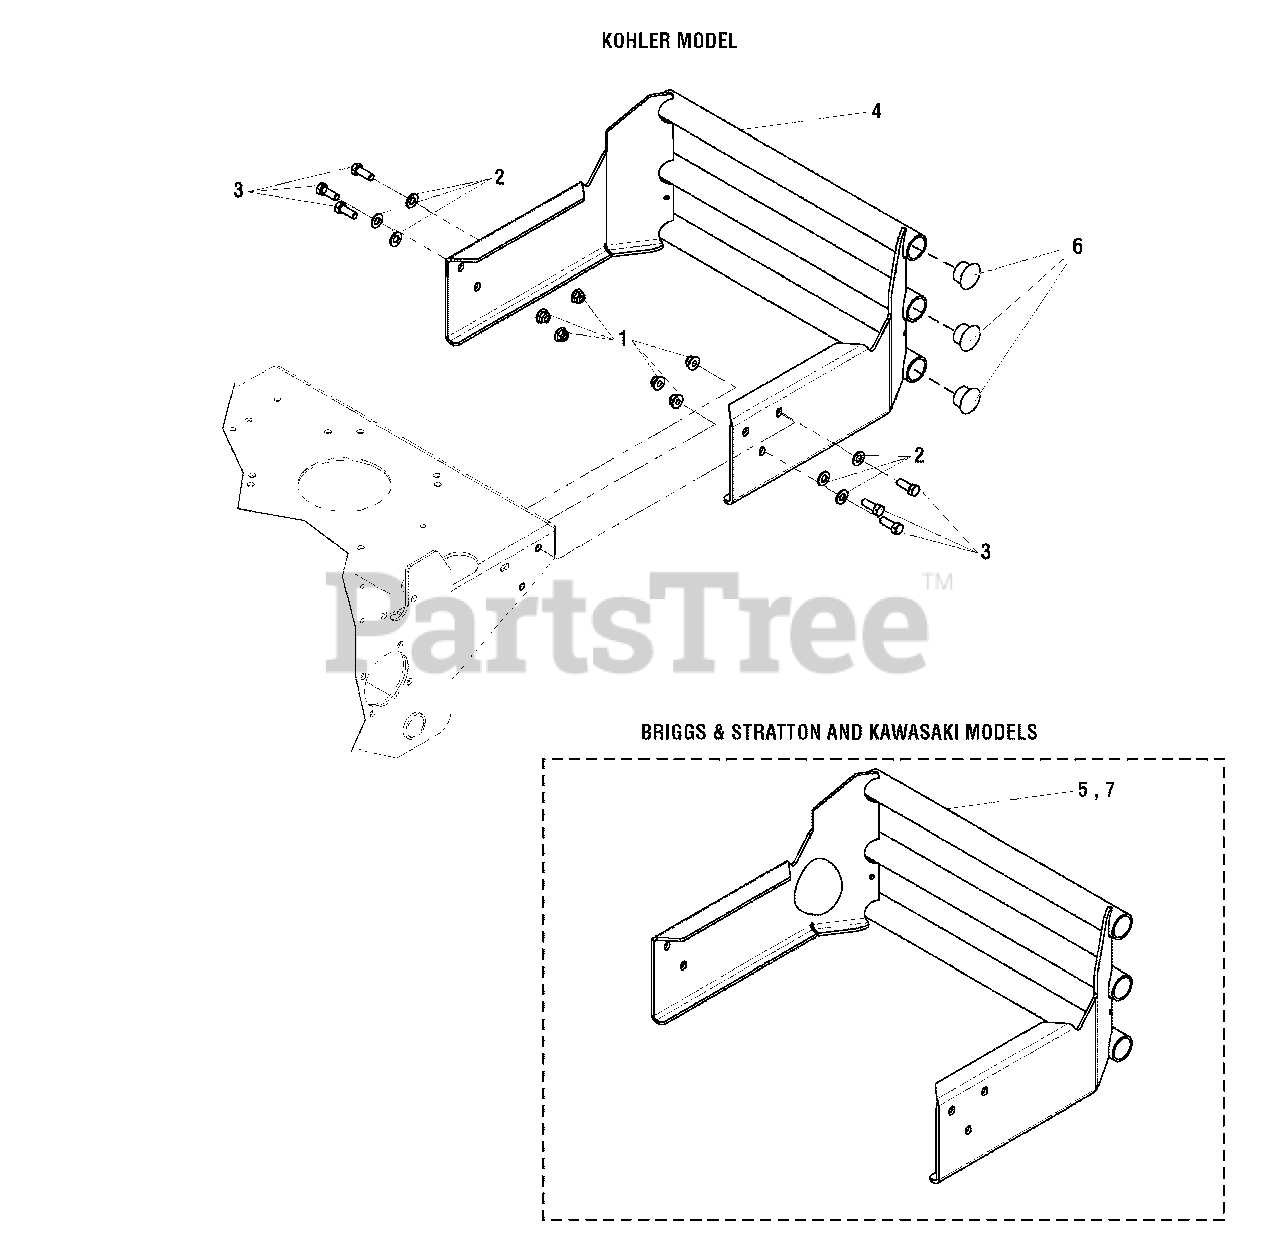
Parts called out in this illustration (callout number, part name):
1	NUT, 3/8-16 HEX NYLOCK FLANGE
2	WASHER, 3/8 SAE
3	BOLT, 3/8-16 X 1" GD5 CZ
4	WELD, BUMPER, SNAPPER Z
5	WELD, BUMPER, SNAPPER Z
6	PLUG, PANEL, 1.25 BLACK
7	WELD, BUMPER, SNAPPER Z
